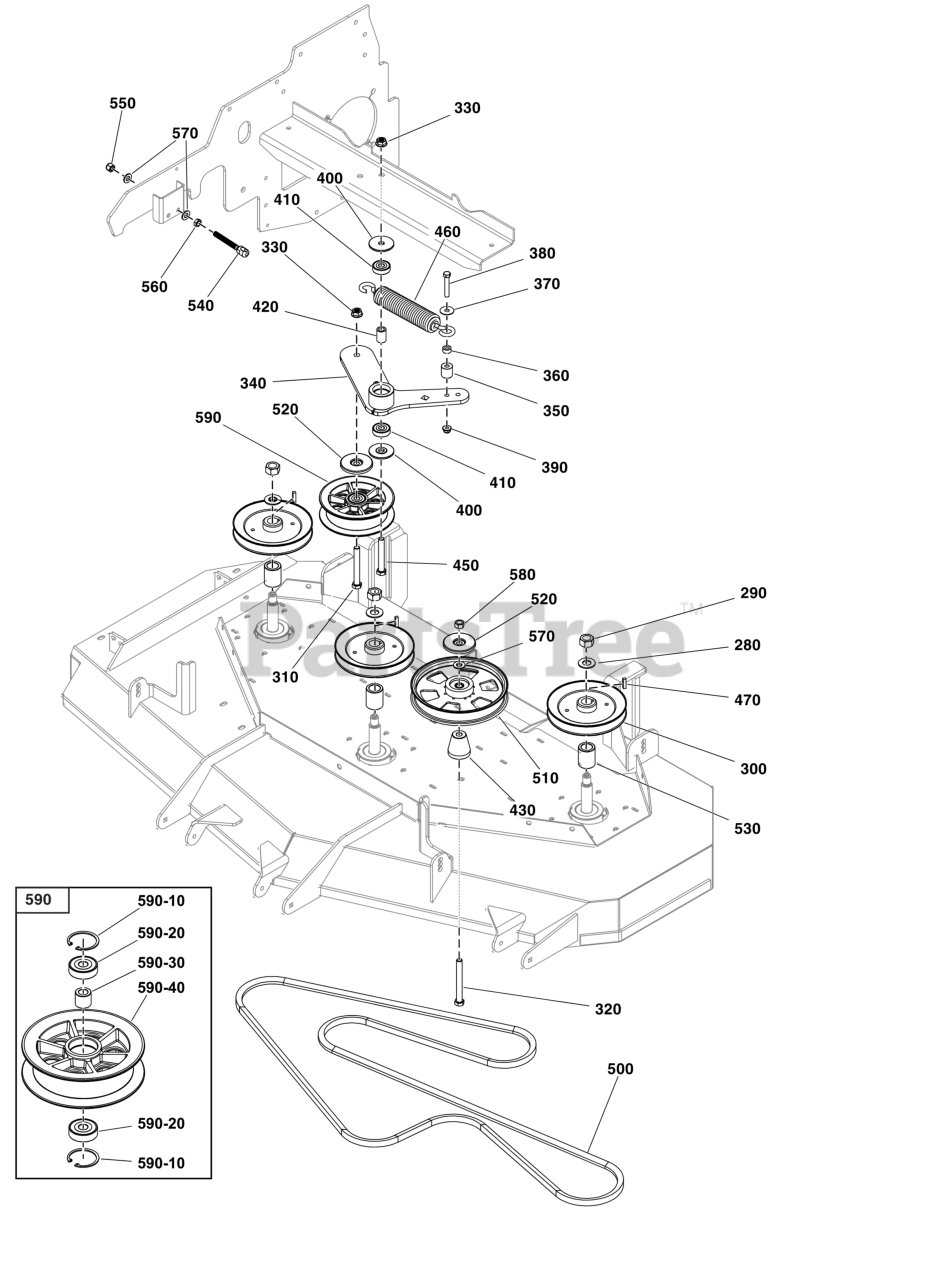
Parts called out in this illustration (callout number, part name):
280	WASHER, Beveled
290	NUT, 3/4-16 HEX
310	BOLT, 1/2-13 X 4 GD5
320	BOLT, 1/2-13 X 4-1/2"
340	ARM, IDLER
360	SPACER, .39 X .75 X .
370	WASHER, 3/8" FENDER
380	BOLT, 3/8-16 X 2-1/4"
390	NUT, 3/8-16 HEX NYLOCK
420	SPACER, .51 X .84 X 1
450	BOLT, 1/2-13 X 3-1/2"
460	SPRING, Extension
470	KEY, 1/4" SQ. X 1.00
510	ARM, IDLER
540	ANCHOR, SPRING
550	NUT, 1/2-20 HEX NYLON
560	NUT, 1/2-20 HEX JAM
570	WASHER, 1/2" SAE
590	PULLEY ASSEMBLY
590-10	RING, SNAP
590-40	PULLEY HOUSING
